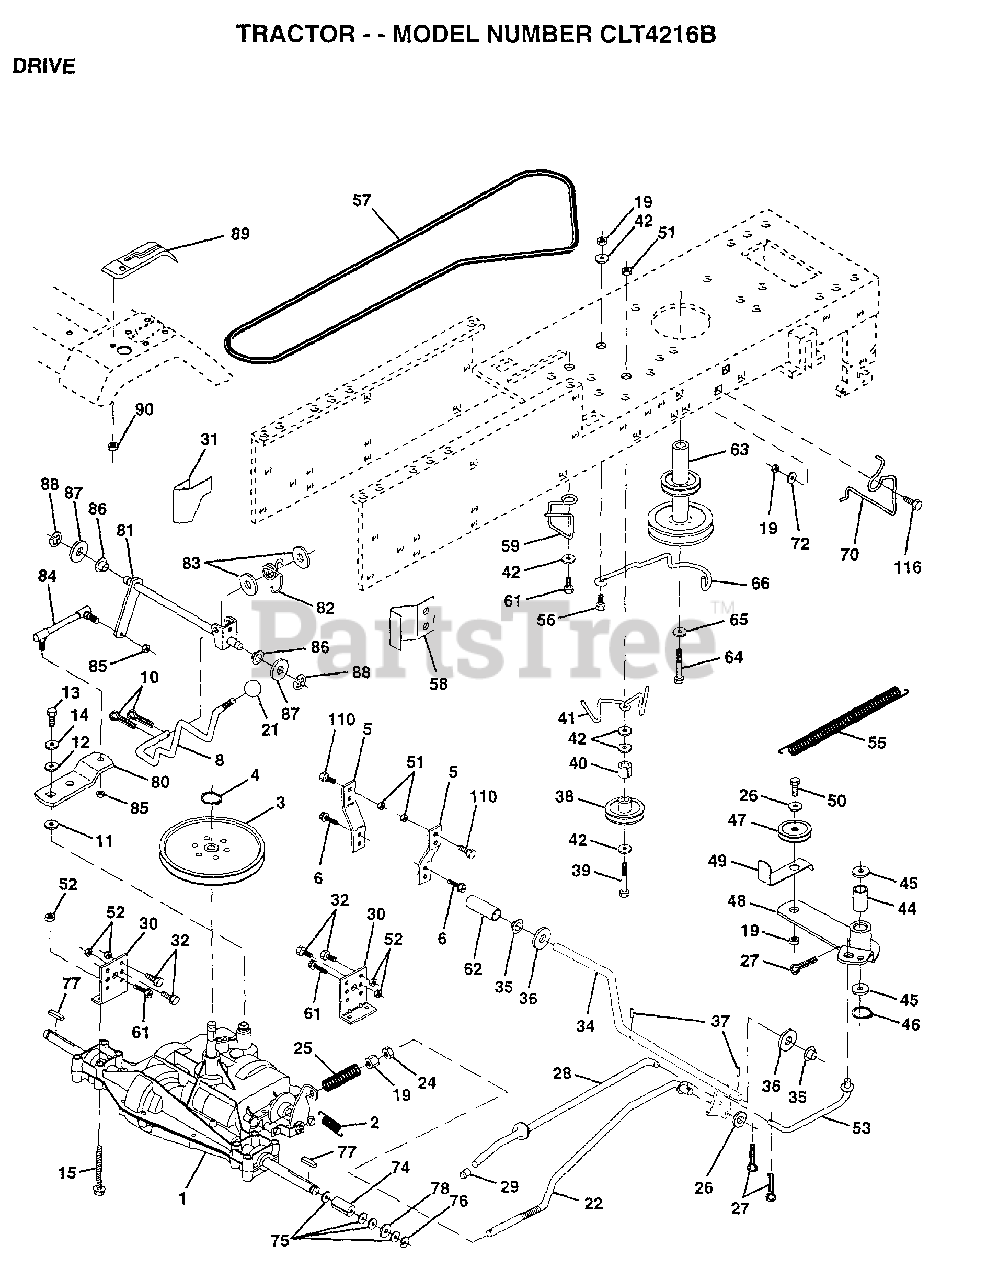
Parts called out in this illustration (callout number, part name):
2	SPRING.BRAKE.RETU
3	PULLEY TRANS
5	STRAP TORQUE
6	SCREW
8	ROD SHIFT FEND LT
10	PIN COTTER 1/8
11	WASH-SHFT PLT LT
12	WASHER
13	BOLT.1/4-28.W/PAT
14	LOCKWASHER
15	BOLT.HX.FLG.5/16
19	NUT
21	KNOB T (1/2-HOLE)
22	BRAKE ROD
24	NUT
25	SPRING ROD LT
26	WASHER
27	COTTER PIN
28	ROD.BRAKE.PARK.LT
29	PLUNGER CAP T
30	TRANSAXLE MTG BKT
31	"KEEPER,BELT LH T"
32	BOLT
34	SHAFT FOOT PEDAL
35	NYLON BEARING
36	WASHER LT
38	PULLEY.IDLER.FLAT
39	BOLT
40	SPACER T
41	KEEPER BELT
42	WASHER
44	"LY, BEARING"
45	WASHER LT
46	KLIP RING
48	ARM IDLER
49	RETAIN BELT
53	"LINK, CLUTCH T"
55	"SPRING, RETURN LT"
58	"KEEPER,BELT RH T"
59	KEEPER BELT CNTSP
61	SCREW
62	PEDAL COVER T
63	PULLEY.ENGINE
64	BOLT
65	LOCKWASHER
70	KEEPER BELT ENG
72	WASHER
74	SPACER LT
75	WASHER
76	E-RING LT
77	SQUARE KEY
78	WASHER
80	ARM SHIFT TRANS
81	SHAFT ASM.SHIFT
82	"SPRING,TORSION"
83	WASHER
84	TIE ROD
85	NUT.CNT.LOCK.1/4
86	BUSHING
87	WASHER D
88	KLIP RING
90	NUT
116	BOLT RDHD 3/8-16
